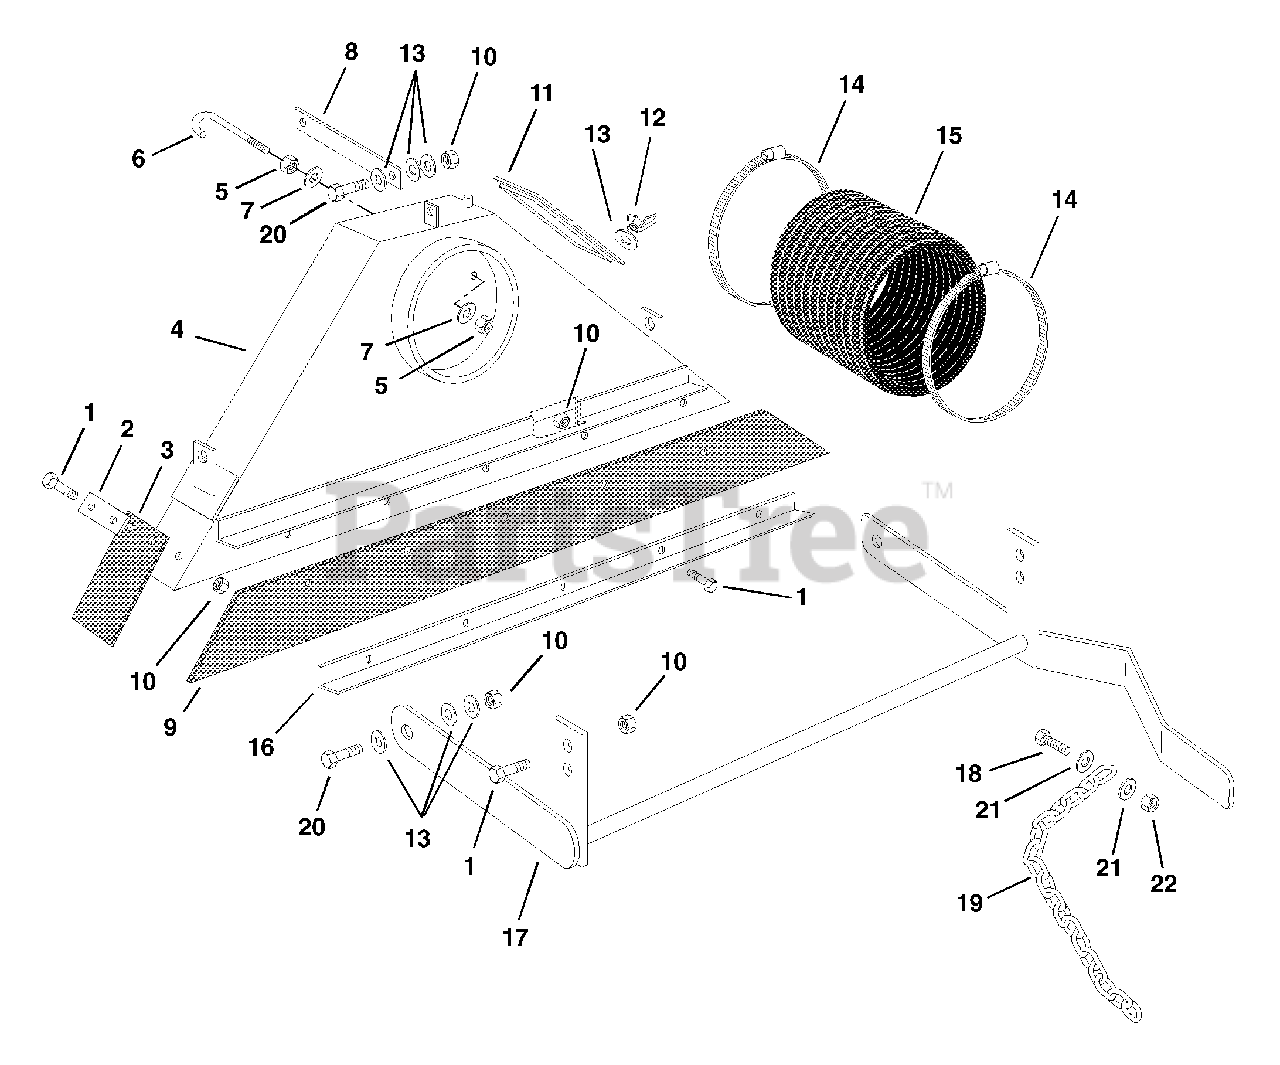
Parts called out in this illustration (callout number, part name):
1	Bolt-Hex .38-16 x 1.00 Grade 5
2	End, Bolting Strip
3	Flex Skirt End Cap
4	Scoop Weldment
5	Nut-Hex .50-13
6	J-Bolt
7	Washer-Flat-Steel .563 x 1.38 x .109
8	Scoop Stabilizer Brace
9	Flex Skirt-Front
9	Flex Skirt-Rear
10	Nut-Locking-Center .38-16
11	Scoop Side Cover
12	Nut-Wing .375-16
13	Washer-Flat-Steel .438 x 1.00 x .083
14	Clamp, Hose #200 13 inch
15	Flex Hose
16	Retainer Strip
17	Scoop Lift Weldment
18	Bolt-Hex .44-14 x 1.25 Grade 5
19	10 Link 1/4 inch Chain
20	Bolt-Hex .38-16 x 1.25 Grade 5
21	Washer-Flat-Steel .50 x 1.25 x .083
22	Nut-Locking-Center .44-14
